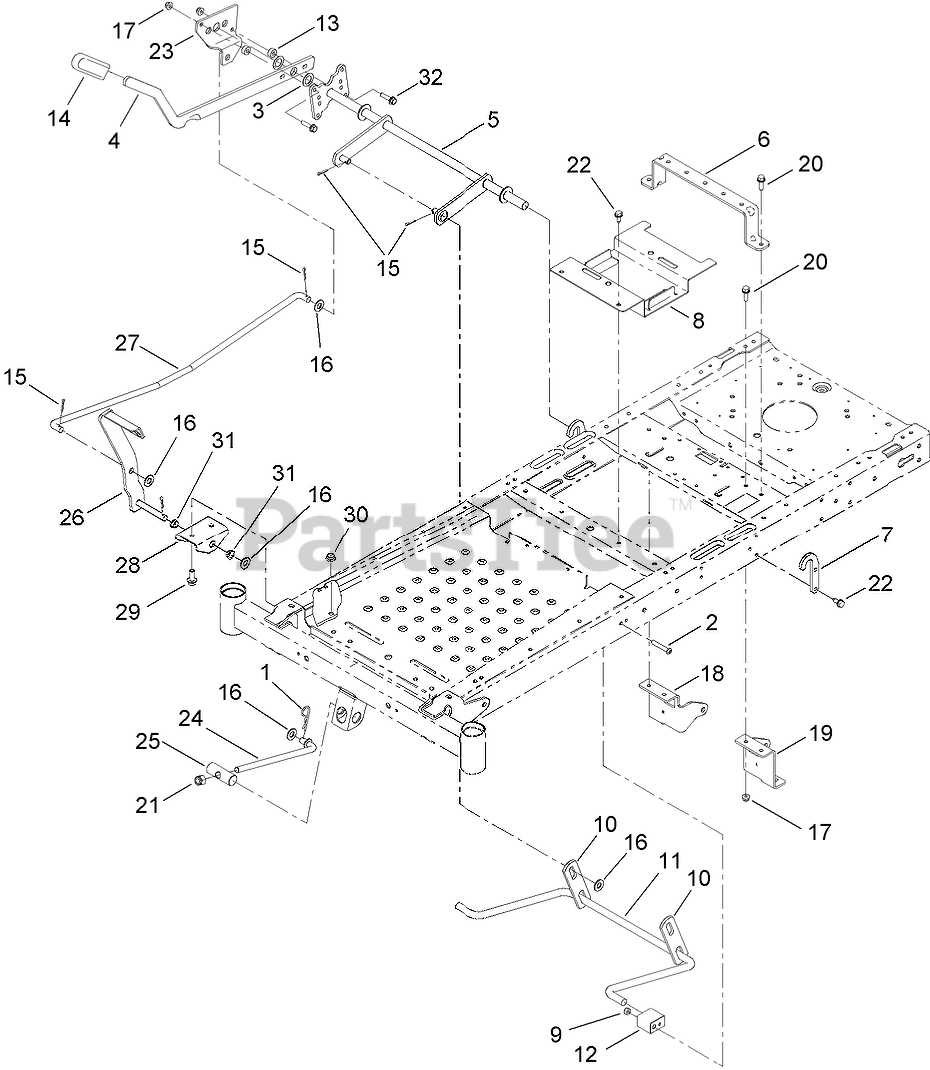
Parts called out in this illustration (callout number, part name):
1	PIN-COTTER
2	SCREW-HSBH
3	WASHER-THRUST
4	LEVER-LIFT
5	LIFT-DECK, NARROW
6	BRACE-SEAT, REAR (NARROW)
7	BRACKET-LIFT
8	BRACKET-BATTERY
9	NUT-LOCK, NI
10	LINK-LIFT
11	ARM-LIFT, REAR
12	BLOCK-PIVOT
13	SPACER
14	GRIP-LEVER
15	PIN-COTTER
16	WASHER-FLAT
17	NUT-HF, NI
18	MOUNT-HYDRO, FRONT (RH)
19	MOUNT-HYDRO, FRONT (LH)
20	SCREW-HHF
21	NUT-HEX
22	SCREW-HWHTF
23	PLATE-FOOTLIFT
24	ROD-TRUNION
25	PIN-PIVOT
27	ROD-FOOTLIFT
28	BRACKET-FOOTLIFT
29	SCREW-HHF
30	NUT-HF, NI
31	BUSHING-FLANGE
32	SCREW-HHF
